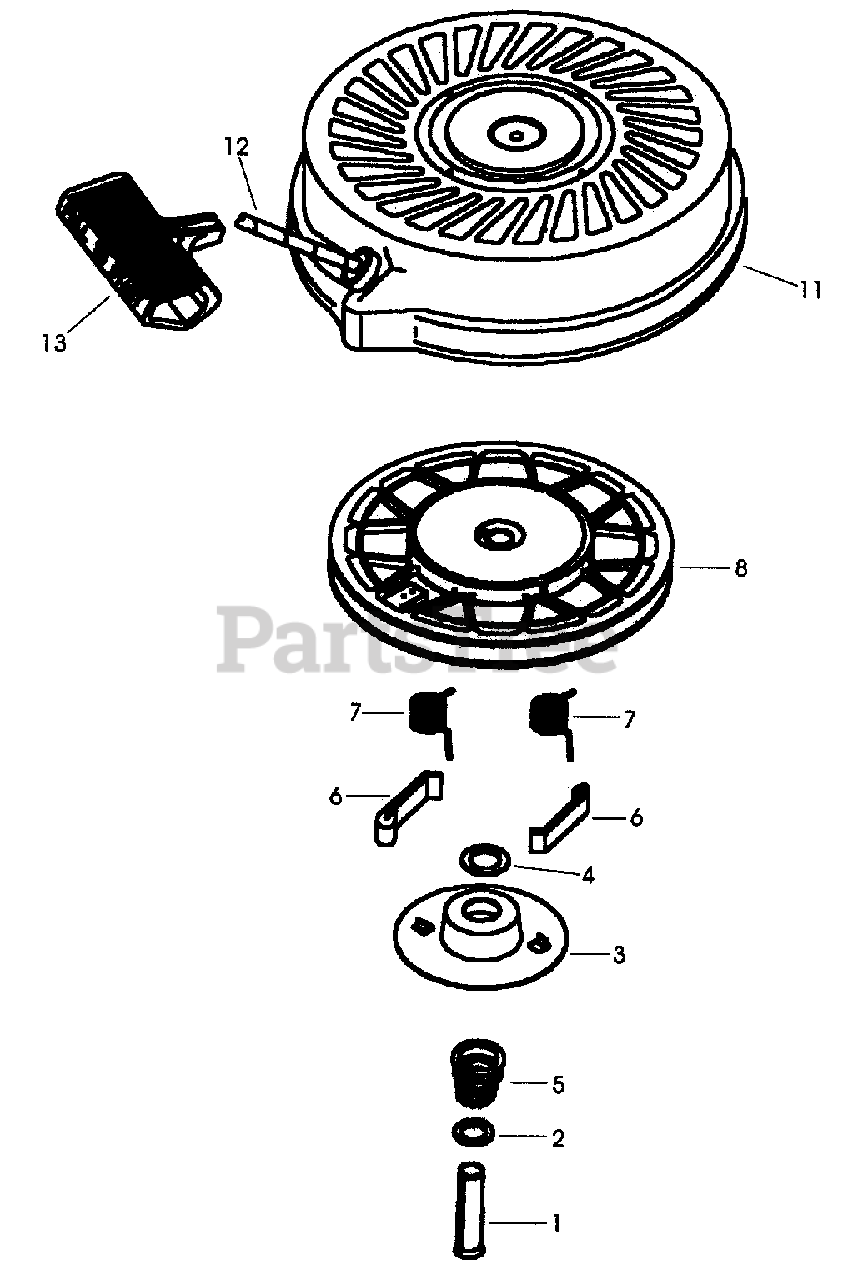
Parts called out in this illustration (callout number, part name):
1	Spring Pin (Incl. 4)
3	Retainer
5	Brake Spring
6	Starter Dog
7	Dog Spring
8	Pulley & Rewind Spring Ass'y.
11	Starter Housing Ass'y (40 degree grommet)
12	Starter Rope ( 98" X 9/64" dia.)
13	Starter Handle
